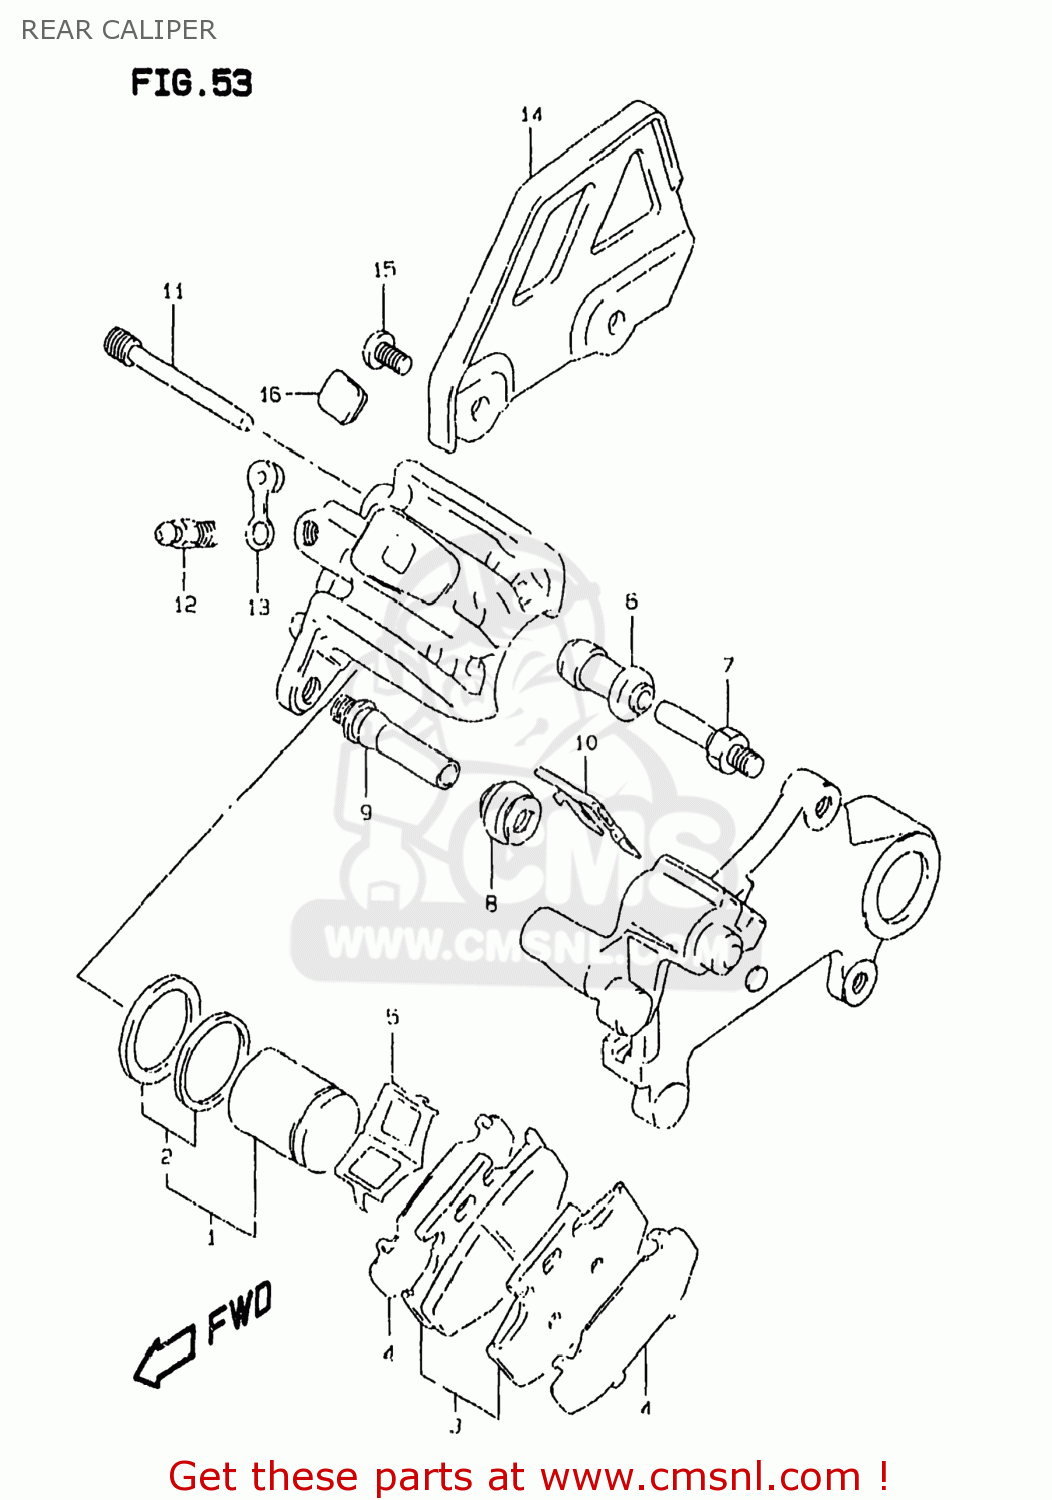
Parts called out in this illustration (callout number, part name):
1	PISTON SET
2	SEAL SET,PISTON
3	PAD SET (NAS)
4	SHIM
5	SPRING,PAD
6	BOOT
7	BOLT
8	BOOT
9	PIN
10	RETAINER,BRACKET
11	PIN,HANGER
12	BLEEDER
13	CAP,BLEEDER
14	GUARD,RR CALIPER
15	SCREW 6X12
16	COVER,RR CALIPER BODY
